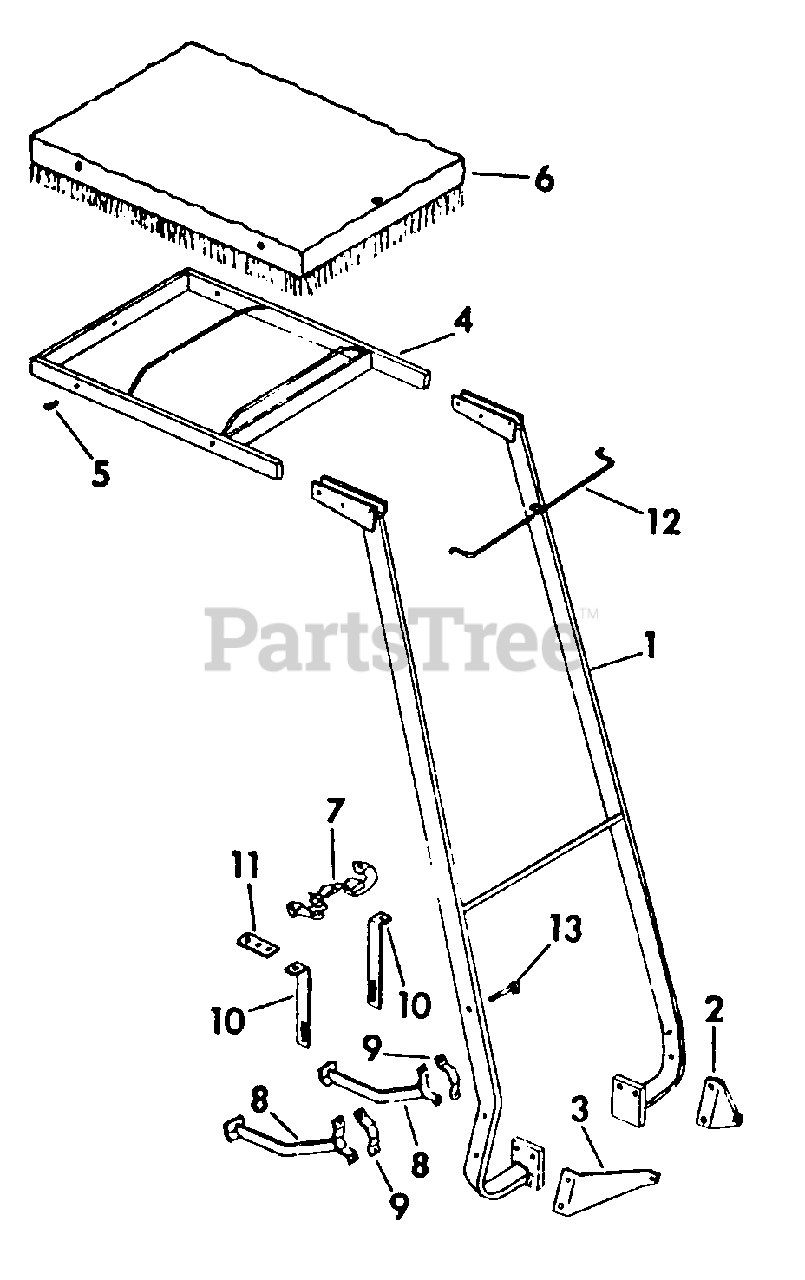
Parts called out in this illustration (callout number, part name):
1	Frame Assy, Lower
2	Bar, LH Frame Stiffener
3	Bar, RH Frame Stiffener
4	Frame Assy, Top
5	Snap, Male
6	Top, Canopy
7	Belt, Seat
8	Bracket Assy, Rear Axle
9	Flange, Caliper Mtg
10	Bracket, Safety Belt
11	Bar, Hitch
12	Rod Assy, Canopy Pivot
13	Eyebolt
